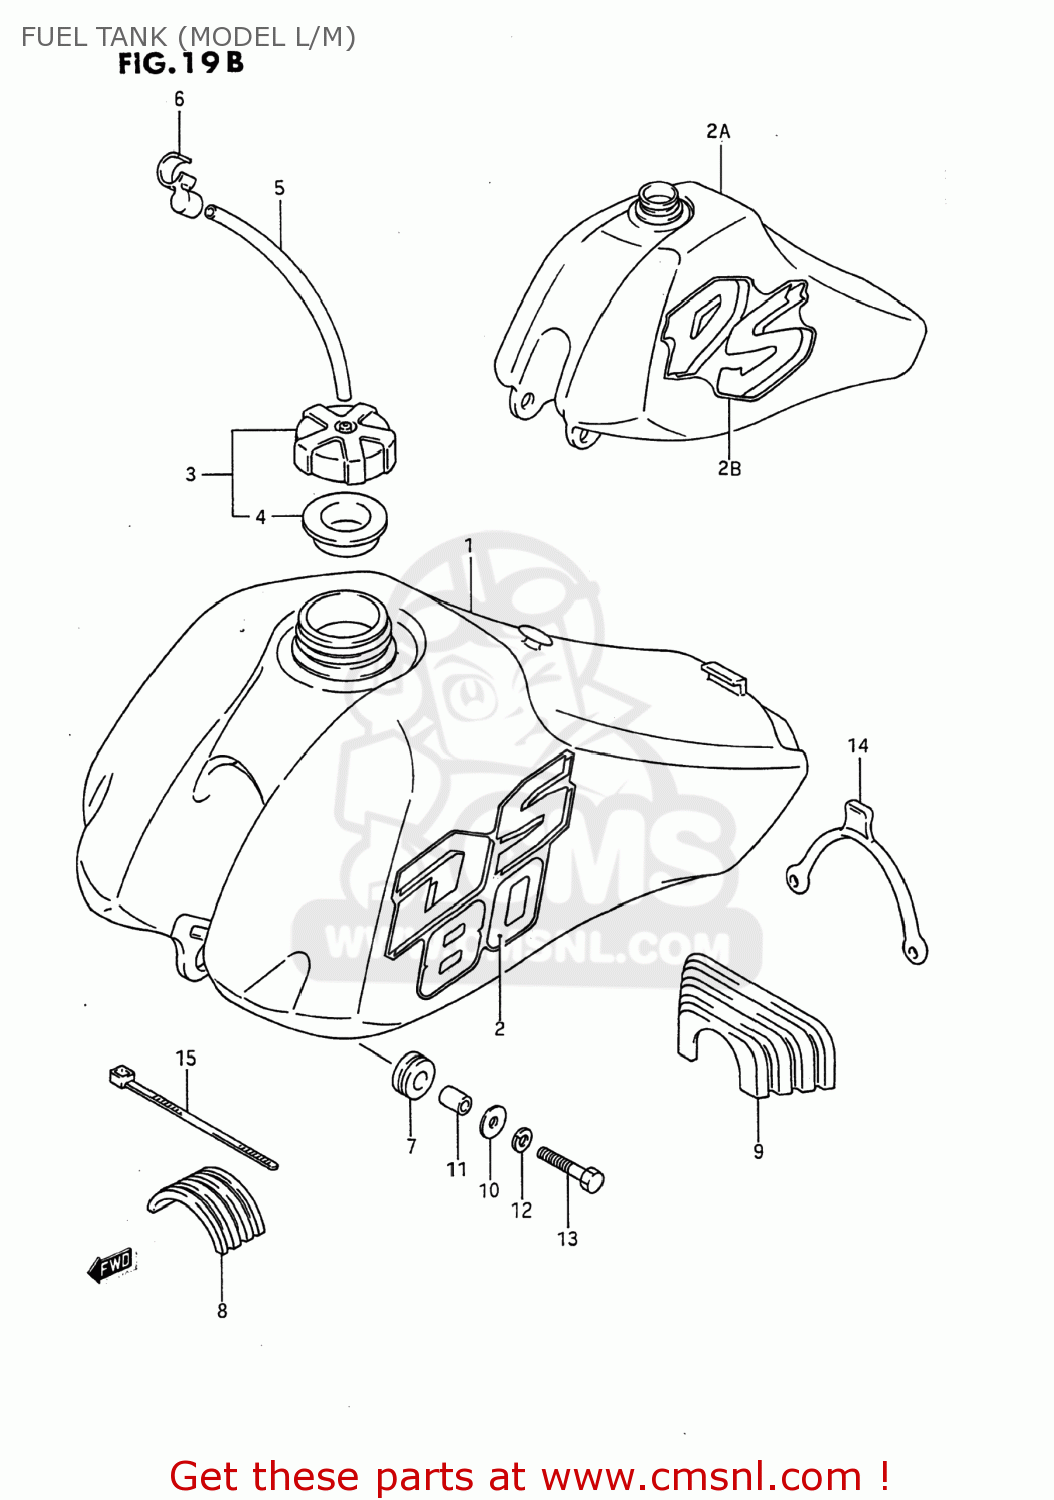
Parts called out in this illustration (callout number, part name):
1	TANK ASSEMBLY,FUEL
2	EMBLEM,FUEL TANK
2A	TANK ASSEMBLY,FUEL
2B	EMBLEM,FUEL TANK,RIGHT
3	CAP SET,FUEL TANK
4	GASKET,FUEL TANK CAP (NAS)
5	HOSE(5X8.2X600)
6	CLAMP
7	CUSHION
8	CUSHION,FUEL TANK UPR FR
9	CUSHION,FUEL TANK UPR RR
10	WASHER (6.5X24X1.6)
11	SPACER (6.5X10.5X13.5)
12	WASHER,LOCK
13	BOLT
14	BAND,FUEL TANK RR
15	CLAMP
